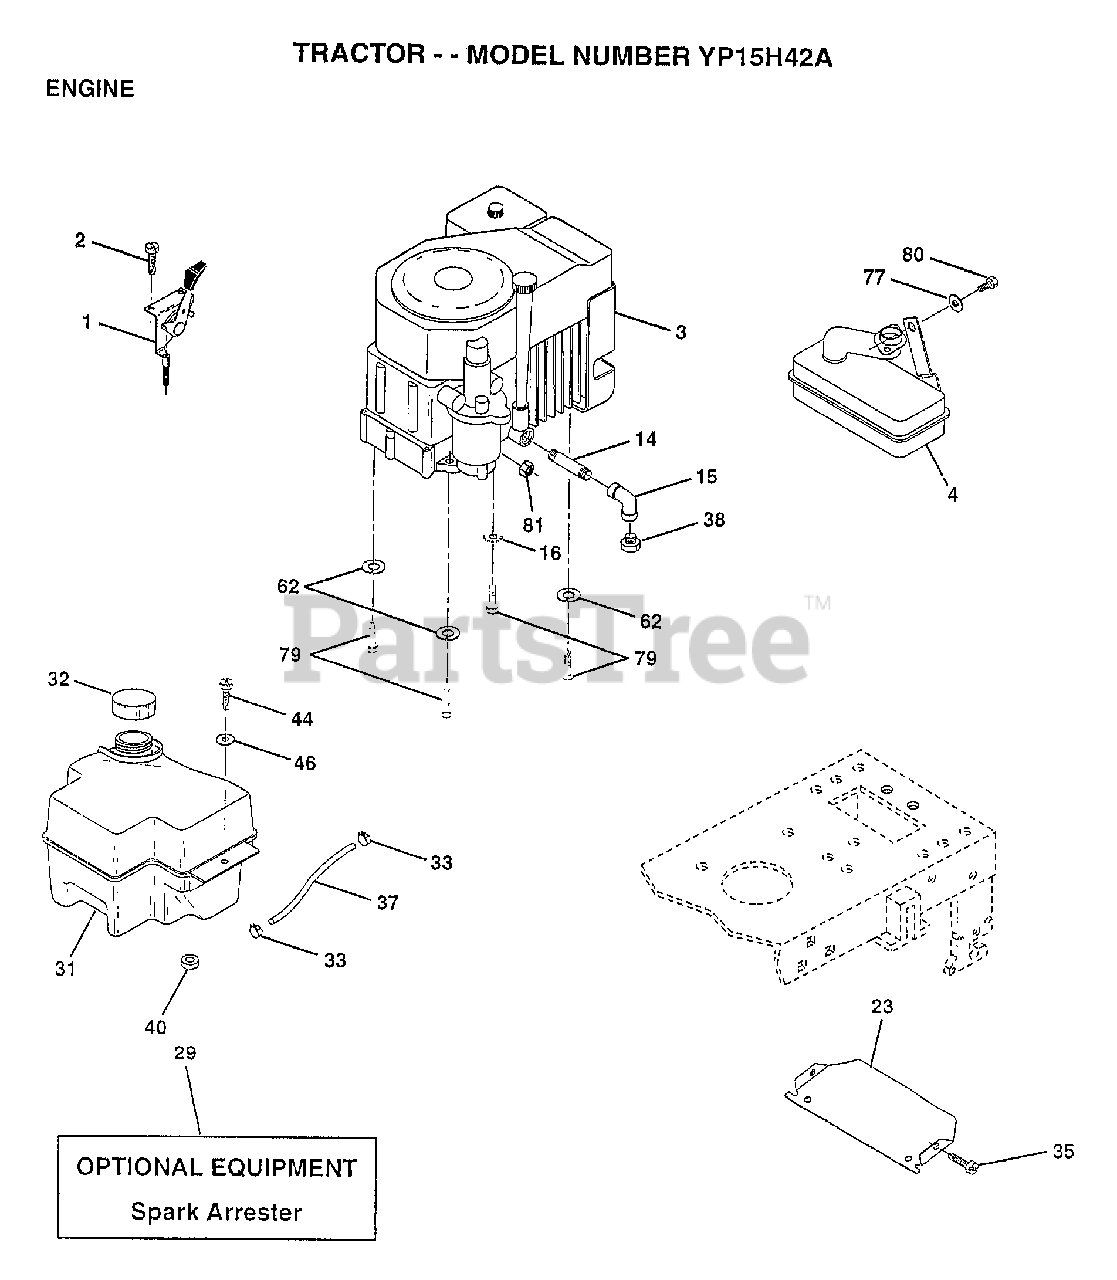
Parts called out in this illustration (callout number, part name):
1	CONTROL.THROTTLE/CHOKE
2	SCREW LT
3	ENGINE KOHLER
4	MUFFLER.LT.12.5
14	PIPE NIPPLE
15	ELBOW
16	LOCKWASHER
23	SHIELD-HEAT
32	CAP ASM FUEL
33	HOSE CLAMP
35	SCREW
37	LINE FUEL
44	SCREW HEX CRT
46	WASHER
62	LOCKWASHER
80	BOLT
81	NUT
